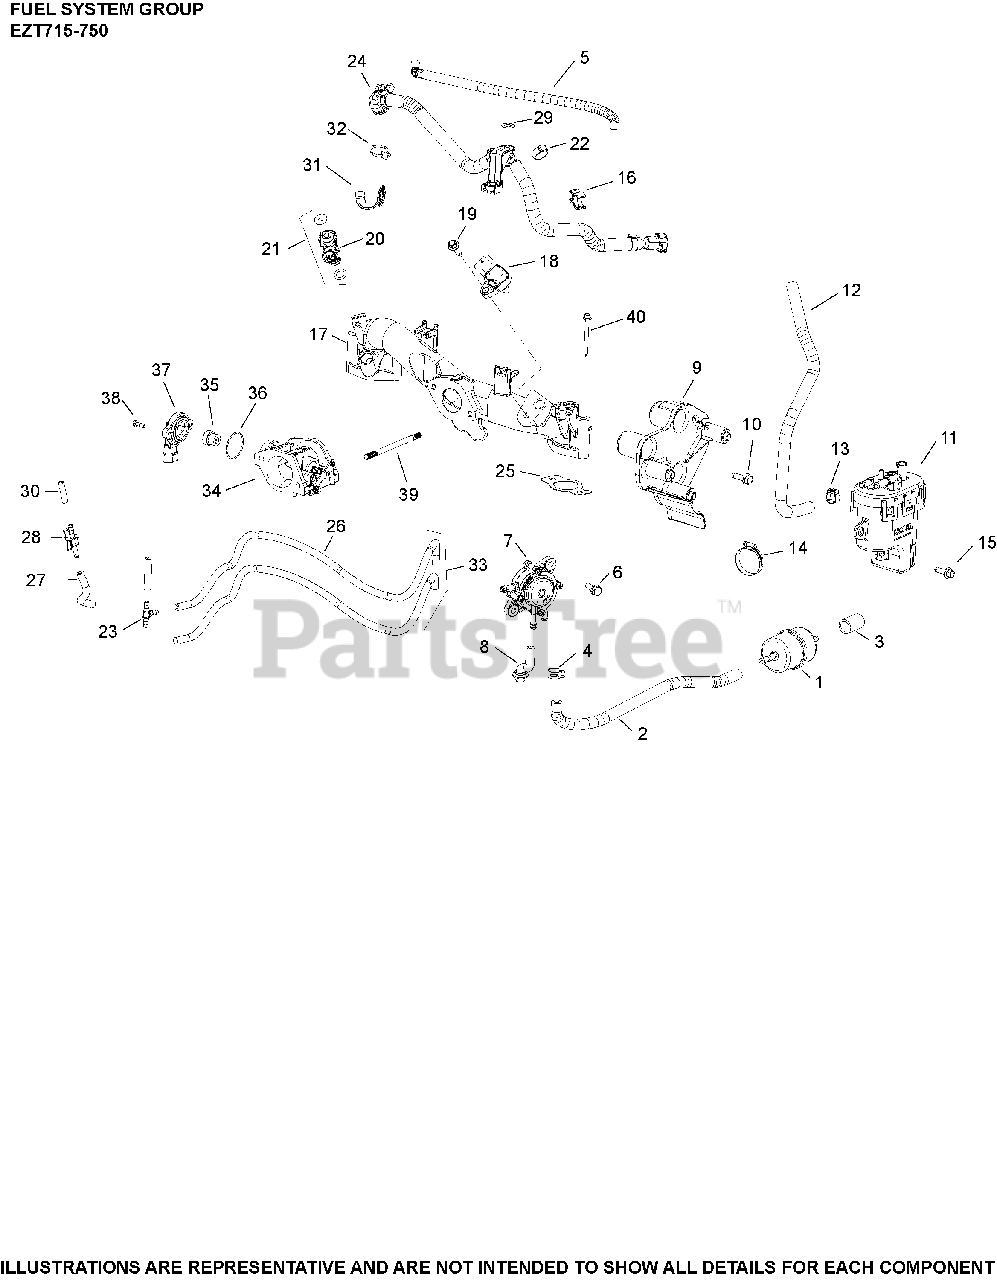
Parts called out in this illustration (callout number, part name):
1	FILTER, FUEL
2	HOSE,LW PERM.FUEL 24.00"-USE 25 111 81-S
4	CLAMP SPRING HOSE
5	SLEEVE, ANTI-ABRASION
6	SCREW, TAP M6X1.7X18
7	PUMP, FUEL (PULSE)
8	HOSE, PULSE PUMP
9	BAFFLE, FUEL MODULE
10	SCREW, THREAD FORMING
11	PUMP, FUEL MODULE
12	SLEEVE, INSULATING
13	CLAMP, OETIKER
14	CLAMP, HOSE (KM)-USE 25 237 31-S
15	SCREW , HEX FLANGE (M6 W/DOG POINT)
16	RETAINER, CLIP
17	MANIFOLD MACHINED (EFI)
18	SENSOR, T-MAP
19	SCREW, FLG M6x1.0x20
20	INJECTOR, FUEL
21	KIT, FUEL INJECTOR O-RING
22	CLAMP, HOSE
23	TEE CONNECTOR
24	RAIL, FUEL ASSEMBLY (ECV,FCV,EZT,EKT)
25	GASKET, INTAKE MANIFOLD
26	HOSE, EVAPORATIVE 20"
27	HOSE EVAPORATIVE (WALBRO)
28	CONNECTOR, EVAPORATIVE
29	CLIP, RETAINER
30	CAP, MASKING
31	CAP, CONNECTOR
32	TIE, CABLE
33	HOSE, ASSEMBLY
34	BODY ASSEMBLY, THROTTLE W/TPS & TS
35	MAGNET, TPS SENSOR
36	O-RING, TPS SENSOR
37	SENSOR, THROTTLE POSITION
